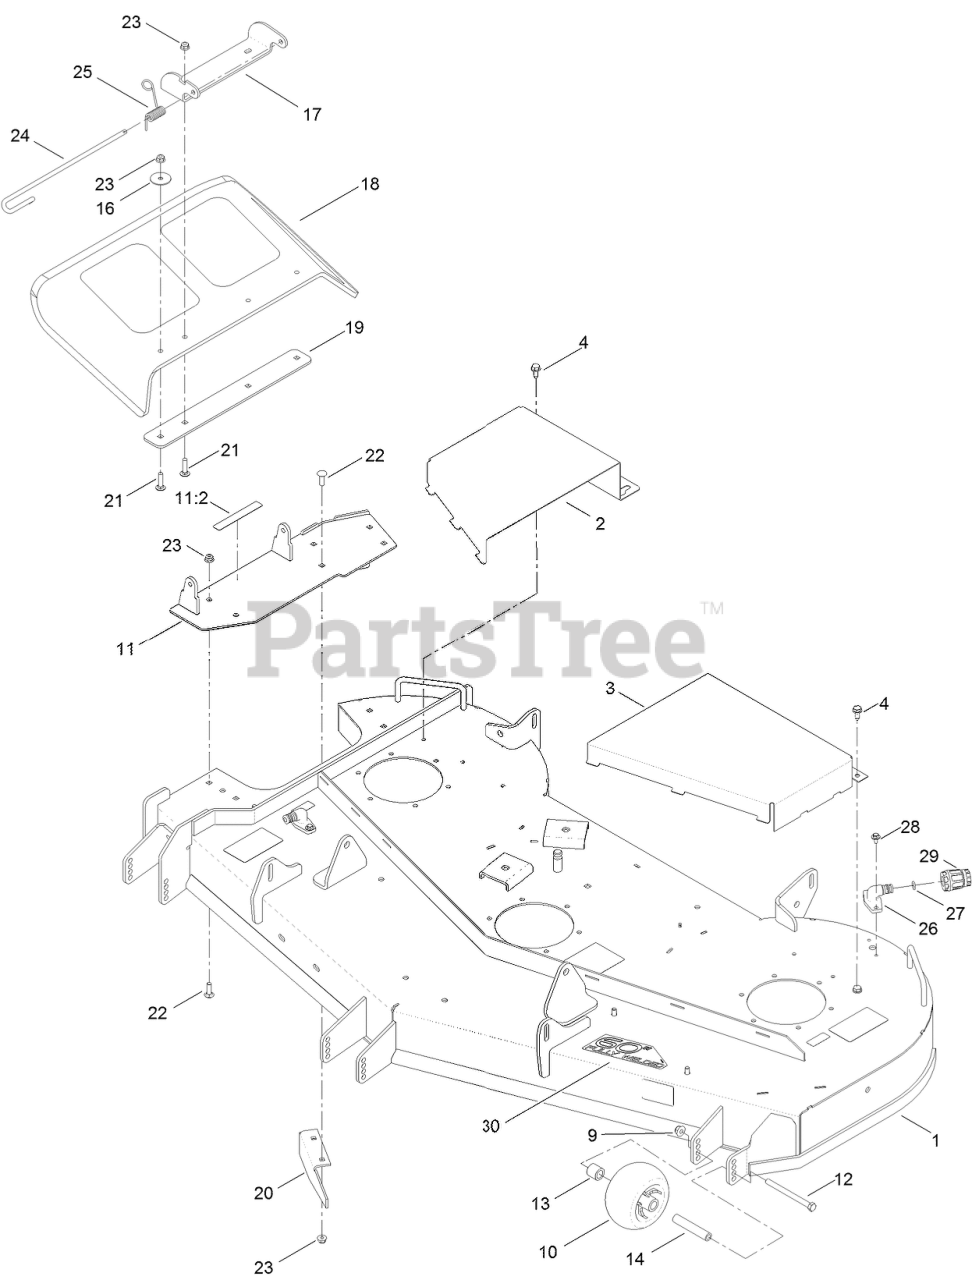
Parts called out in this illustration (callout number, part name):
1	54 INCH DECK ASM
2	COVER-BELT, RH 54 INCH
3	COVER-BELT, LH 54 INCH
4	SCREW-HWHTF
9	NUT-HF, NI
10	ROLLER-SCALP, ANTI
11	PIVOT-DEFLECTOR
11:2	DECAL-DANGER
12	SCREW-HH
13	SPACER-AXLE, REAR
14	TUBE-SPANNER
16	WASHER-FLAT
17	BRACKET-DEFLECTOR, UPPER
18	DEFLECTOR
19	PLATE-DEFLECTOR
20	BAFFLE-CUTOFF
21	SCREW-CARR
22	SCREW-CARR
23	NUT-HF, NI
24	PIN-CHUTE
25	SPRING-TORSION
26	FITTING-WASHOUT
27	O-RING
28	SCREW-HHFTF
29	CONNECTOR-HOSE
